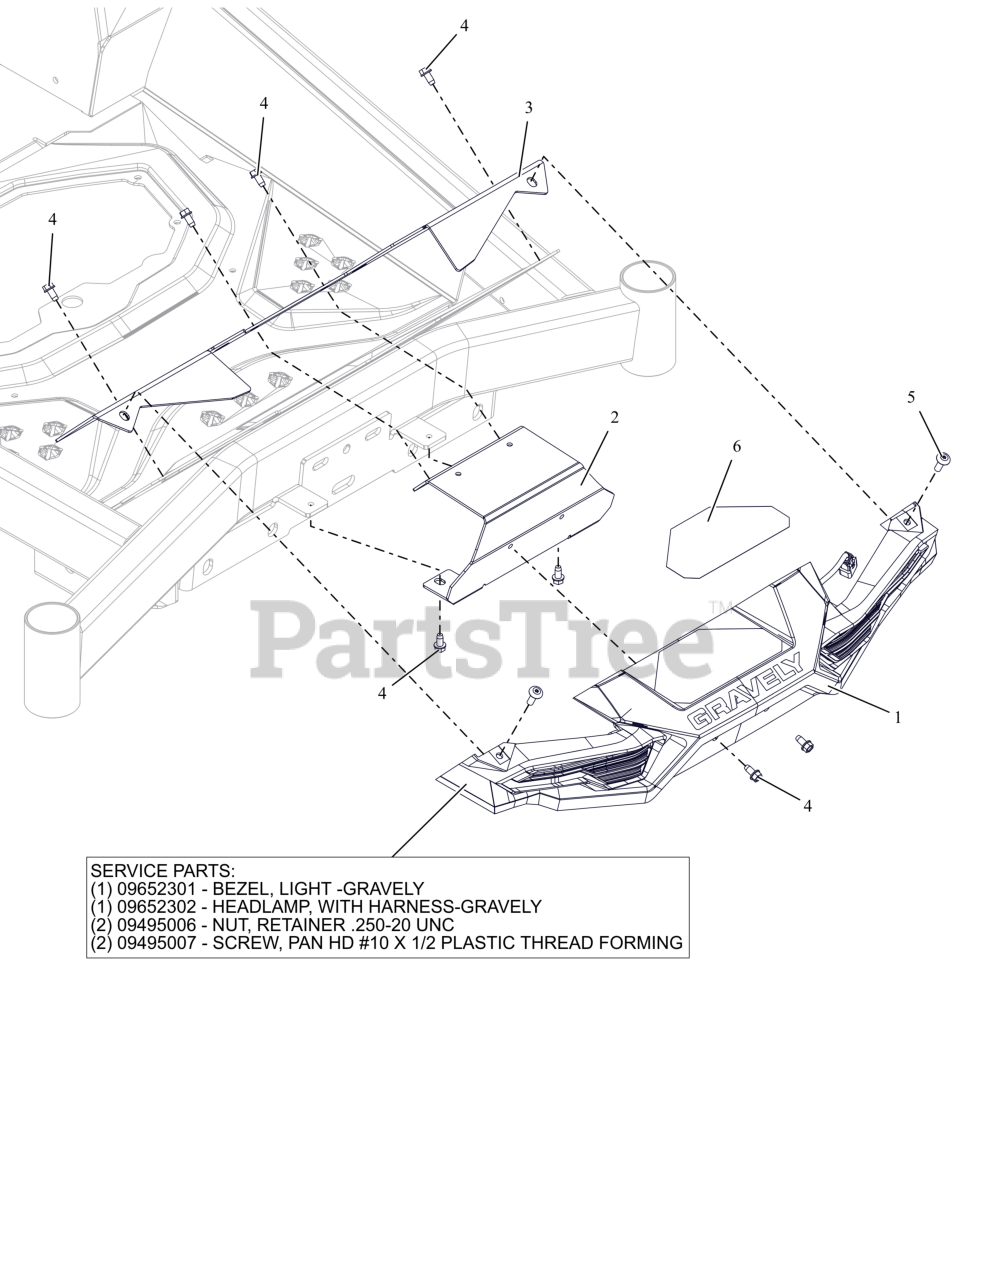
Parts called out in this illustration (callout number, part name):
1	LIGHT ASSY- HEADLIGHT GRAVELY
1	BEZEL LIGHT-GRAVELY
1	HEADLAMP- WITH HARNESS-GRAVELY
1	NUT, RETAINER .250-20 UNC
1	SCREW, PAN HD #10 X 1/2 PLACTIC THREAD FORMING
2	BRKT-FRT FACIA-LOWER-GRAVELY
3	BRKT- FRT FACIA UPPER-GRAVELY
4	SCR-TAP .25X.50 HWH ZB500
5	SCR-MCH .25-20X.75 TXTR ZB500
6	GRIP- TAPE-FRONT STEP-GRAVELY
